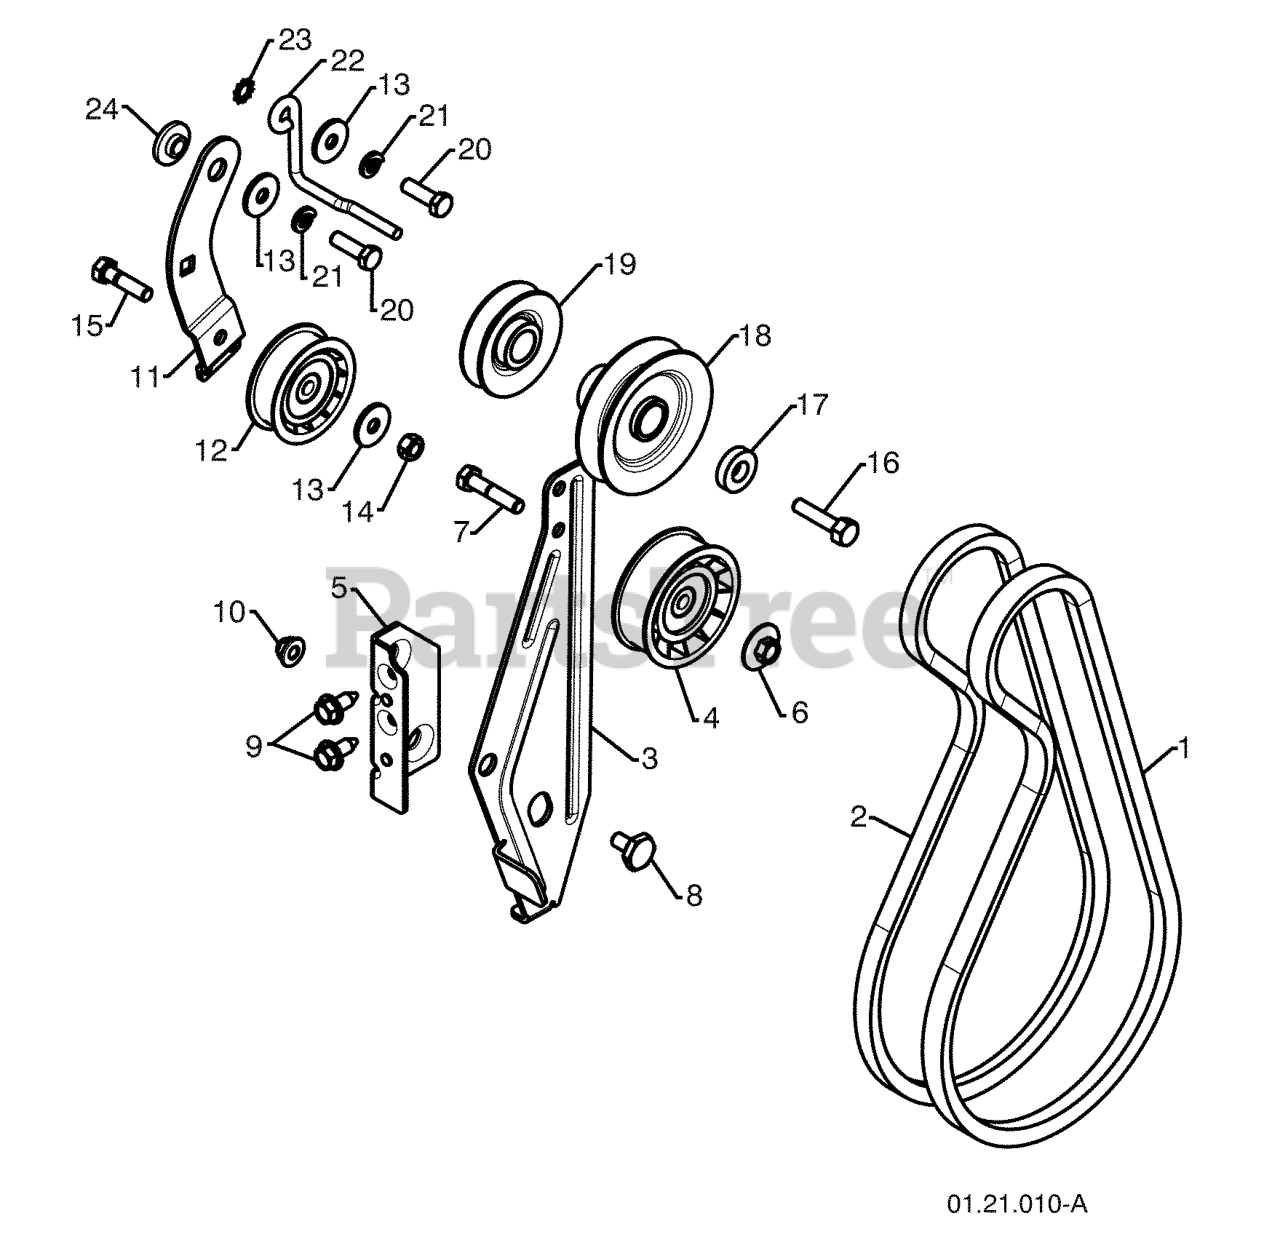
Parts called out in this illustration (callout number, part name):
1	VBELT; IMPELLER_39.09
2	V-BELT.TRACTION.HYDRO
3	ARM.IDLER.BRAKE.
4	PULLEY.W/SPACER.2.75
5	RP BRACKET.IDLER.PIVOT
6	NUT.FLANGE.HEX.5/16X18.BLACK
7	HEX BOLT
8	BOLT.SHOULDER.1/2X12
9	BOLT.HEX.HD.WASHER.5/16-18X.75
10	NUTNYLOK.FLRANGE.5/16-18
11	ARM, IDLER
12	PULLEY.W/SPACER.2.25
13	STEEL WASHER
14	NUT.CENTERLOCK.5/16-
15	BOLT.5/16-18X1-1/4 FULL.THREAD
16	SCREW, HEX HD 3/8-24 X 1-3/8
17	WASHER, FLAT 3/8
18	PULLEY.ENG.IMPELLER.SNOW
19	PULLEY.ENG.TRACTION
21	WASHER.LOCK.HVY.HLCL.SPR.5/16
22	GUIDE, BELT
23	WASHER EXT TOOTH LOCK 5/16
24	RP BUSHING, IDLER PIVOT
